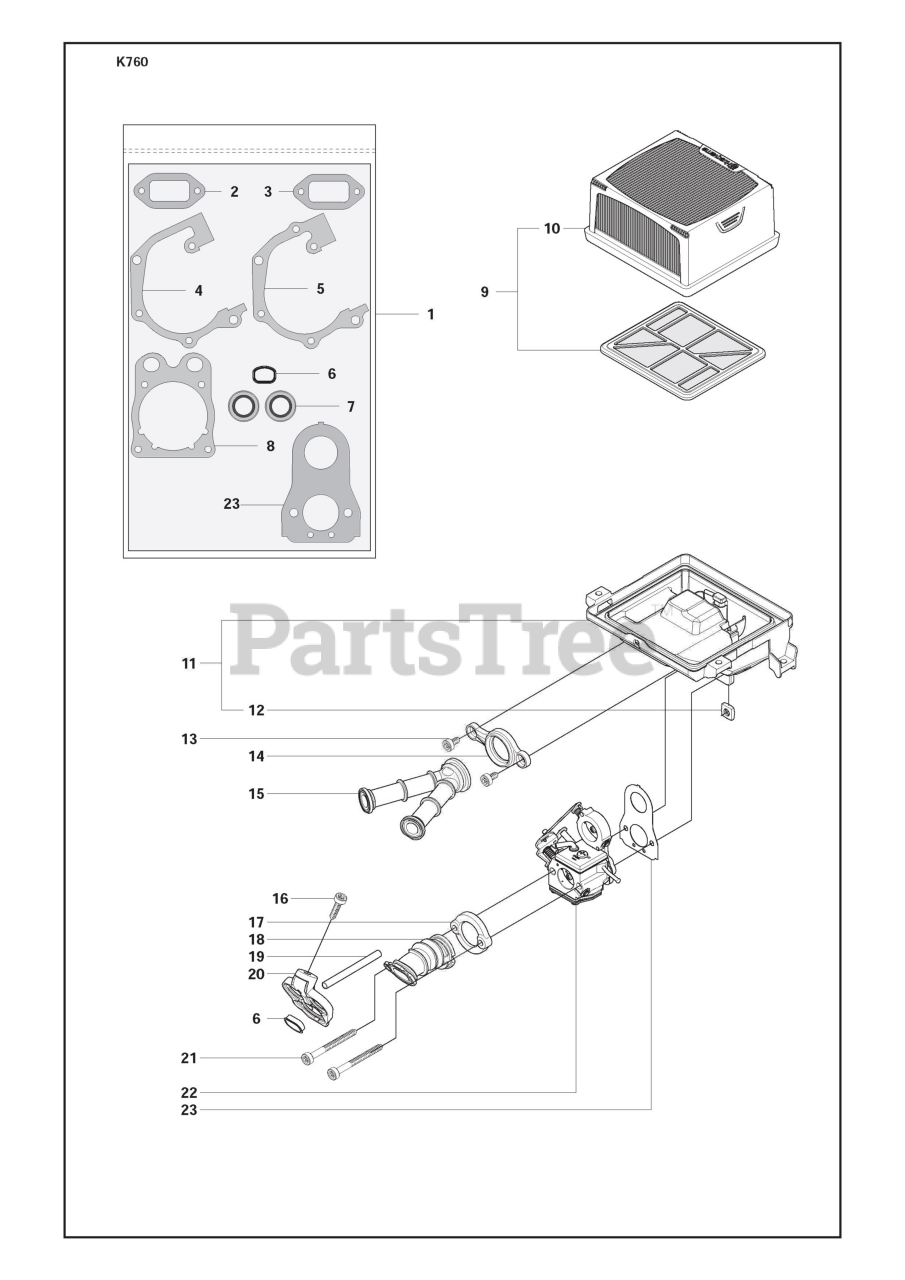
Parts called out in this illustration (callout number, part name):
1	Gasket Kit
3	Gasket Muffler
4	Gasket Crankcase
5	Gasket Crankcase
7	Sealing Ring
8	Cylinder Base Gasket
9	Filter
10	Air Filter Paper
11	Carburettor Bracket
14	Flange Inlet Pipe
15	Inlet Pipe
17	Flange Inlet Pipe
18	Inlet Pipe
19	Impulse Hose
22	Carburettor
23	Gasket Carburettor
